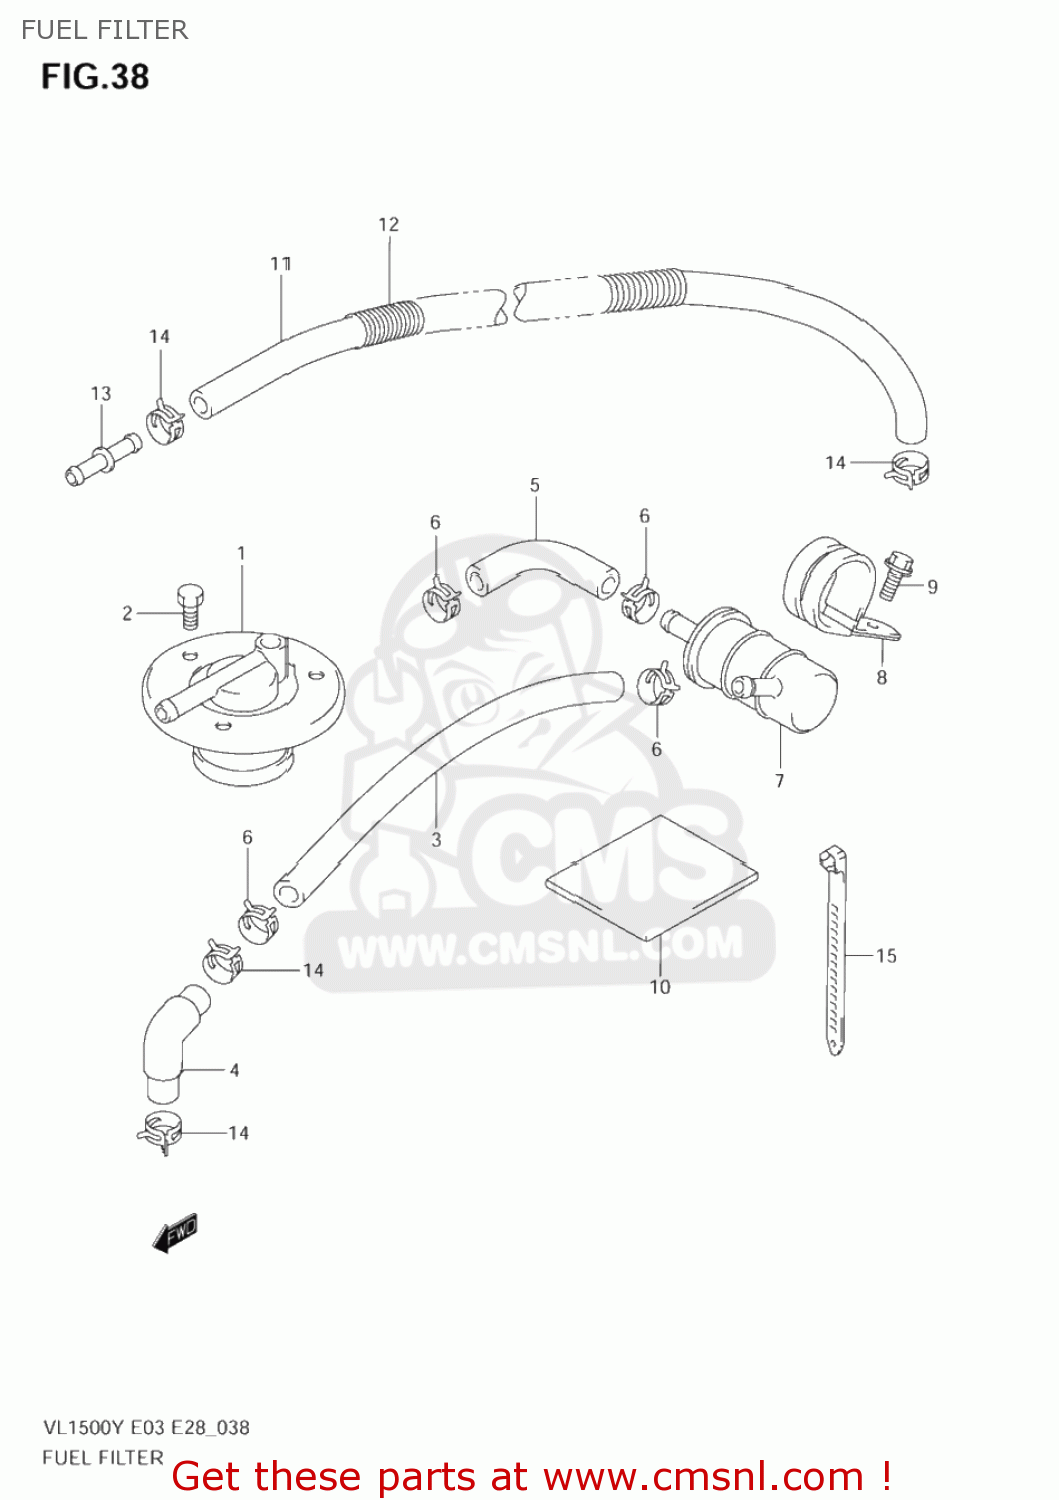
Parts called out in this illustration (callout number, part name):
1	VALVE,FUEL CUT
2	BOLT 5X10
3	HOSE(7X12X600)
4	JOINT,FUEL HOSE
5	HOSE,FUEL TANK & FILTER
6	CLIP
7	FILTER,FUEL
8	CLAMP,FUEL FILTER
9	BOLT
10	CUSHION,FILTER FITING
11	HOSE(7X12X600)
12	SPRING
13	JOINT
14	CLIP
15	CLAMP(L:165)
